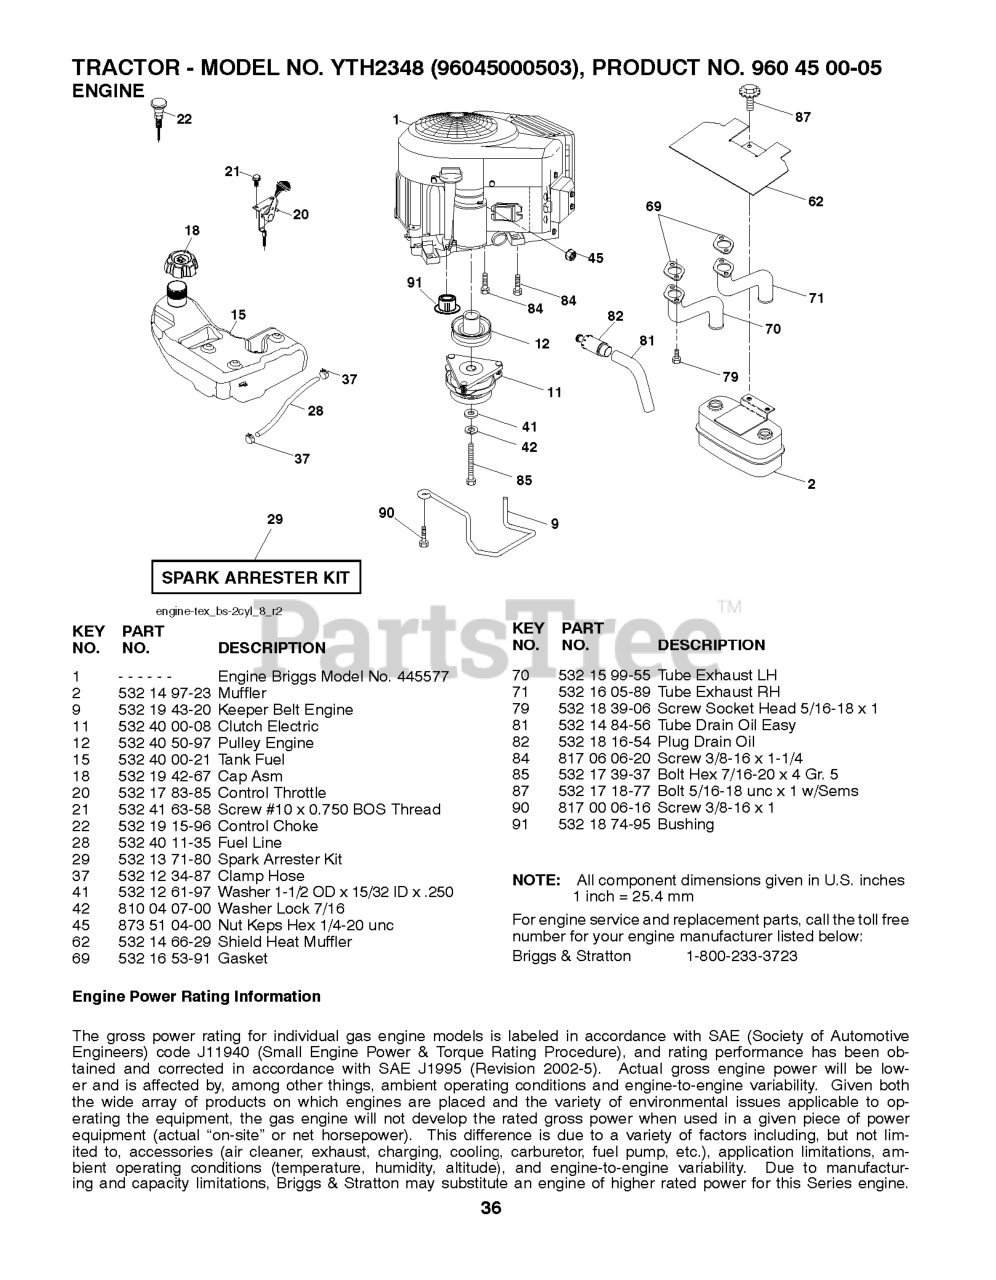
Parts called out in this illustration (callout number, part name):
2	MUFFLER.TWIN.CYL.LOW.TONE
9	KEEPER.BELT.ENGINE.4.2
11	CLUTCH.ELECTRIC.LT.48"*
12	PULLEY.ENGINE.TUFFTORQ
15	TANK.FUEL.SIDE-FILL.3.NON-EPA
18	CAP.FUEL.TANK.3"GREY
20	THROTTLE CABLE
21	SCREW.#10 X 0.750.BOS
22	CONTROL.CHOKE.ERGO.PUSH-IN.BLA
28	LINE.FUEL.64"REAR.EMIS
29	KIT.SPARK ARRESTOR 794945 B&S
37	HOSE CLAMP
42	LOCKWASHER
45	NUT
62	RP SHIELD HEAT MUFFLER
69	GASKET.MUFFLER
70	RP.EXHAUST.TUBE.LH.BS/TWIN
71	EXHAUST.TUBE.RH.BS/TWIN
79	SCREW.SOCKET.HEAD.5/16-18
81	TUBE, DRAIN OIL ASM.
82	PLUG DRAIN OIL EASY
84	SCREW.3/8-16
85	BOLT HEX 7/16-20X4-1/4"
87	BOLT.5/16-18UNCX3/4 W/SEMS.BLK
90	SCREW 3/8-16X1
91	BUSHING.1.375OD
